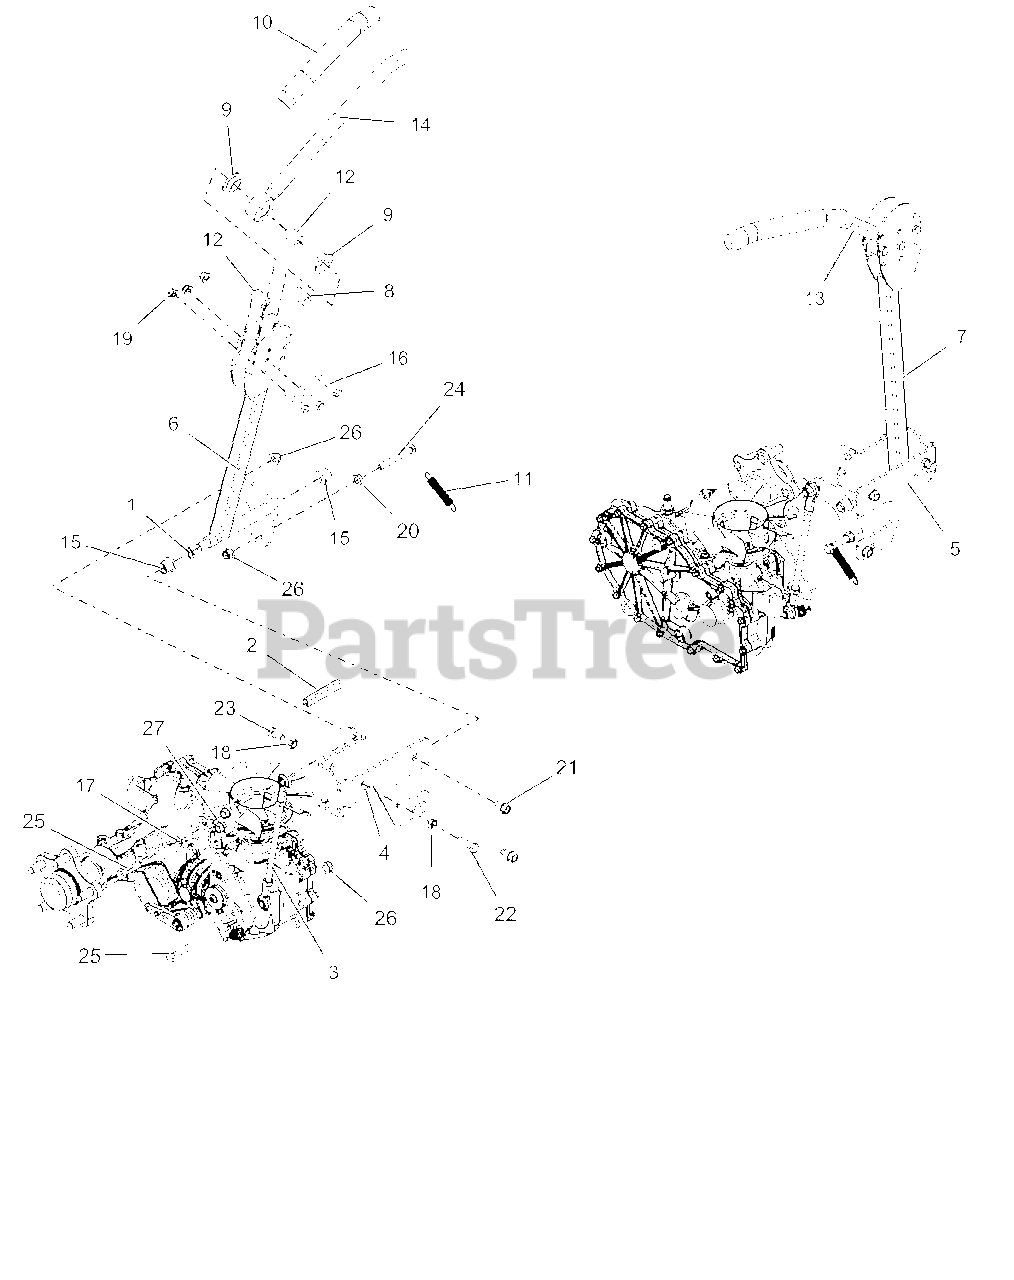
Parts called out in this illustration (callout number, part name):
1	WAVE WASHER .531X.781X.125FH
2	STRIP, COWL
3	ASM, STEERING LINKAGE
4	RH STEERING STOP BRKT - BLK
5	BRKT, LH STEERING STOP
6	WMT-RH PT/PT100 CONTROL ARM-BL
7	WMT-LH PT/PT100 CONTROL ARM-BL
8	BSHG, ECCENTRIC .328X.750X.970
9	BSHG-FLG .762X1.48X.44 NYL
10	GRIP-HANDLEBAR .750IDX11.125LG
11	SPRING,EXT,.061X.50X3.0
12	SPACER .328 X .76 X 1.01
13	HANDLE WLDMT LH
14	WLDMT, RH HANDLE
15	BHSG-FLG .500X.750X.750X.125
16	@BLT-HEX .31-18X1.75 GR5 YWZC
17	@WSHR-LK .38X.094 REG YWZC
18	NUT-HEX-JAM .375-16 YWZC
19	@NUT-LK-NYL-FLG .31-18 YWZC
20	@NUT-SPNLK-FLG .375-16 YWZC
21	@SCR-TAP .38-16X.75 HWH TR YWZ
22	@BLT-HEX .38-16X1.25 GR5 YWZC
23	@BLT-HEX .38-16X.75 GR5 YWZC
24	@BLT-HEX .38-16X2.75 GR5 YWZC
25	@BLT-HEX .38-16X1.50 GR5 YWZC
26	@NUT-LK-NYL-FLG .38-16 YWZC
27	@SCR-TAP .38-16X.50 HWH TR YWZ
